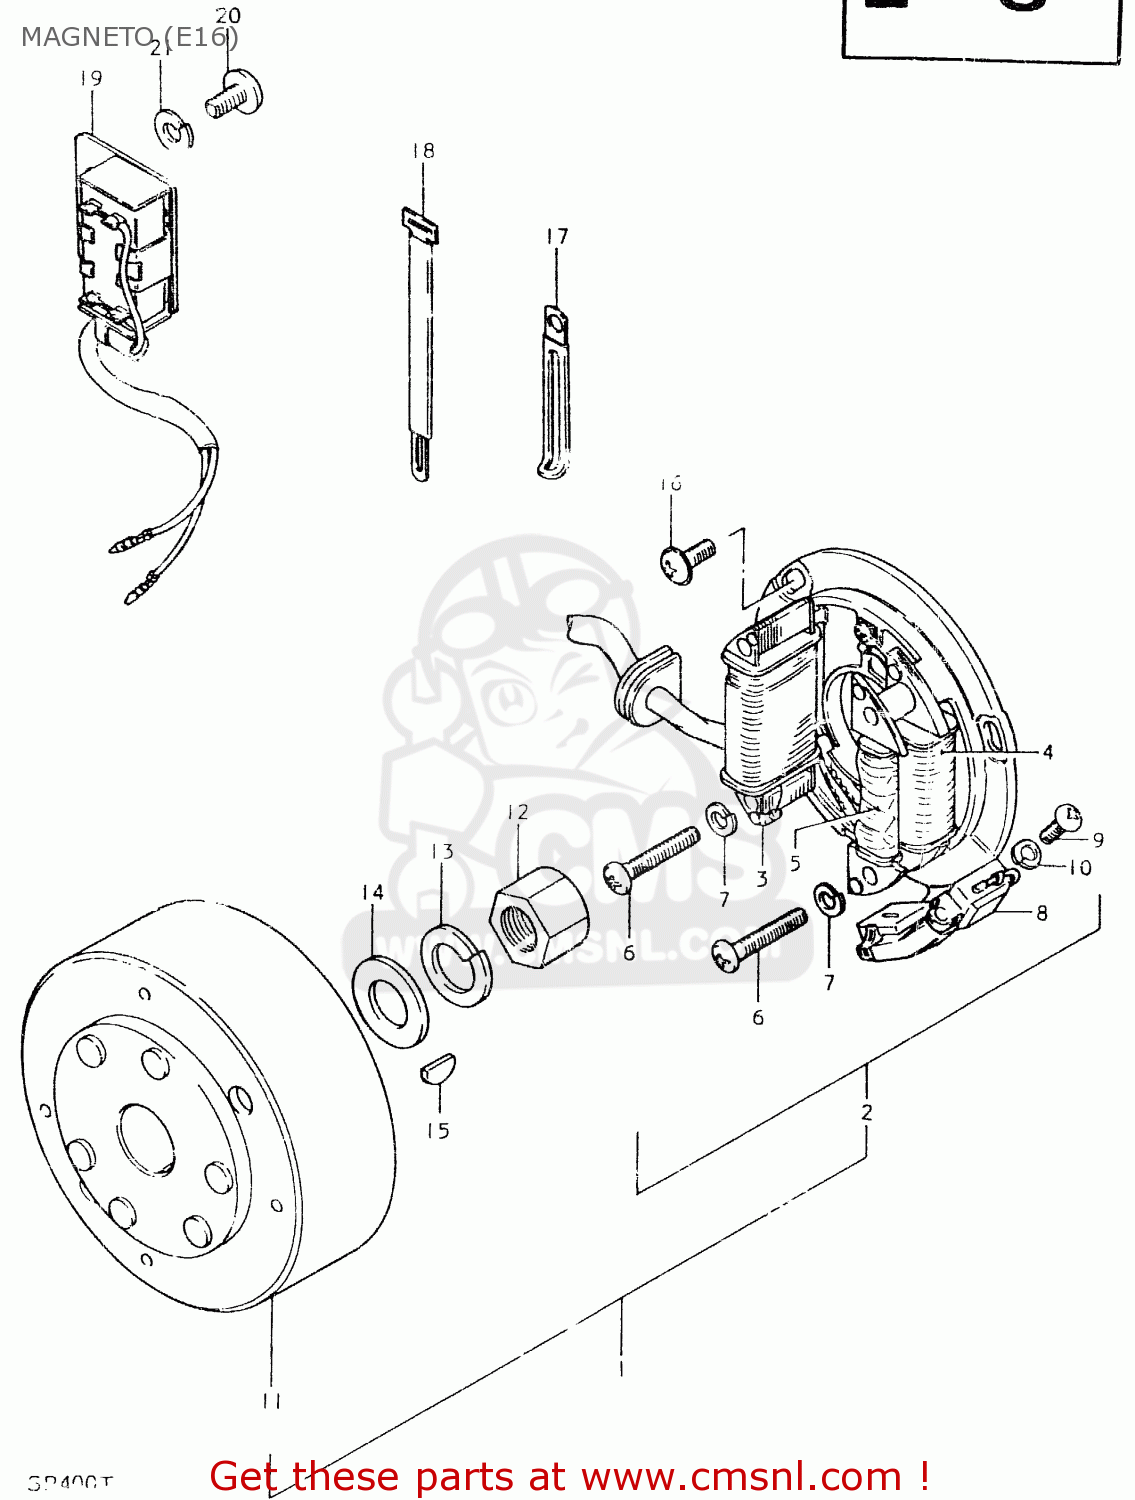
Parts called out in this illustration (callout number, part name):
1	MAGNETO ASSY
2	STATOR ASSY
3	COIL, LIGHTING
4	COIL,PRIMARY
5	COIL,PULSER
6	SCREW
7	LOCK WASHER
8	COIL,PULSER
9	SCREW
10	LOCK WASHER
11	FLYWHEEL, MAGNETO
12	NUT
13	LOCK WASHER
14	WASHER(14X27X3)
15	KEY 4MM
16	SCREW(5X14)
17	CLAMP
18	CLAMP
19	REGISTER ASSEMBLY
20	SCREW 6X12
21	LOCK WASHER
